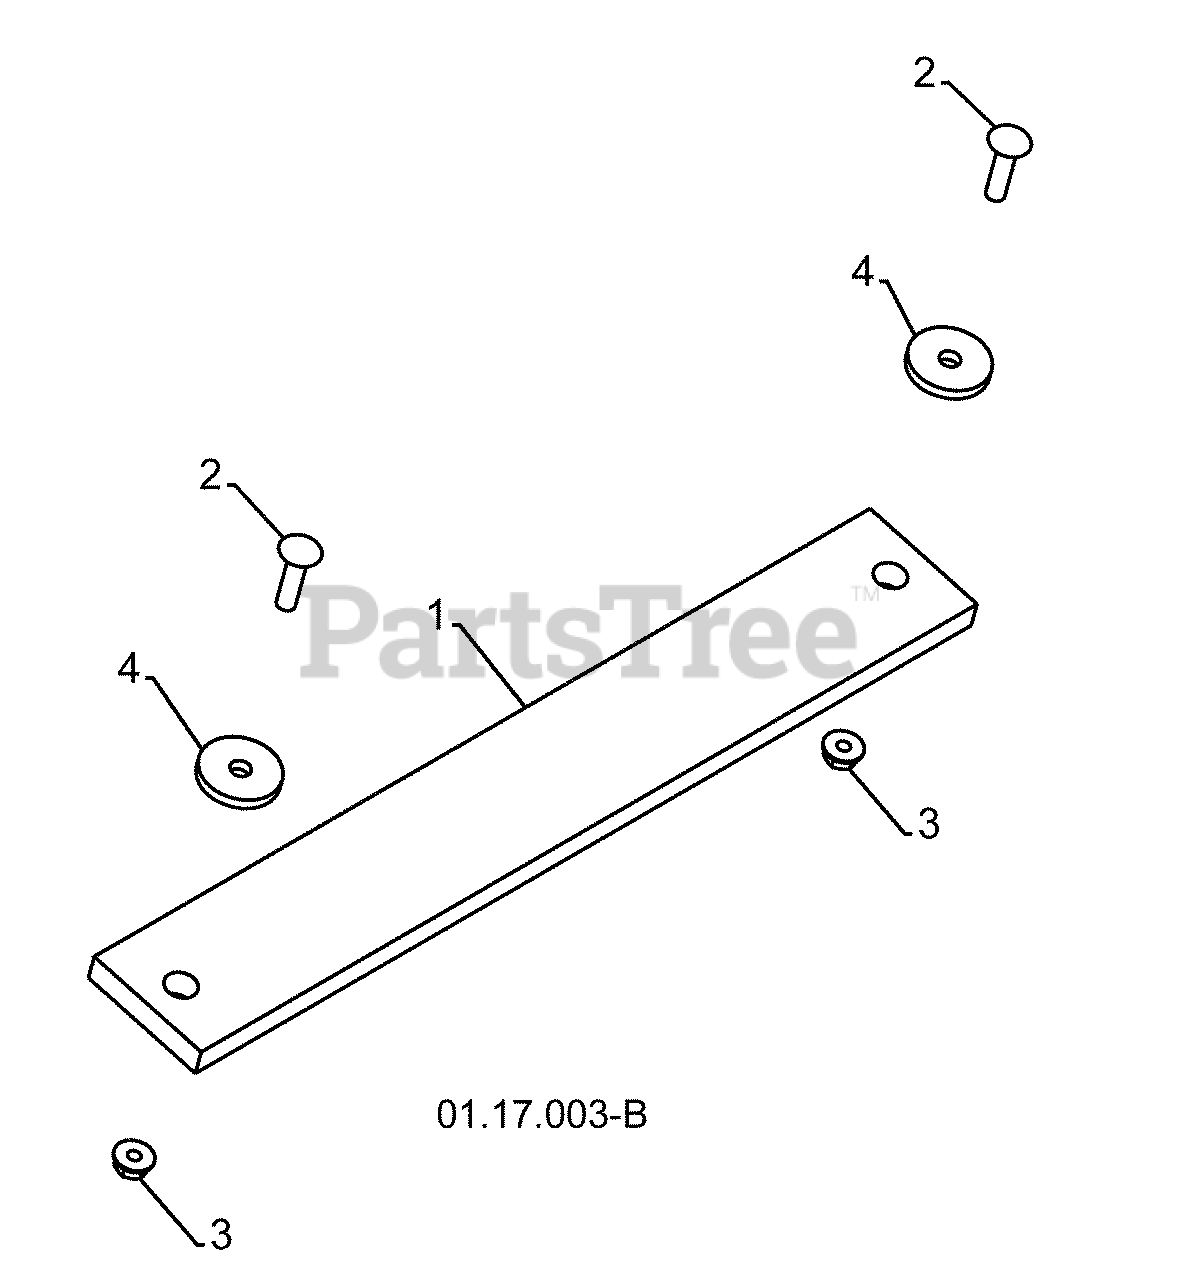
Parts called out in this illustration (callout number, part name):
1	WEIGHT BAR
2	CARRIAGE BOLT 5/16-18 X 1.25
3	NUT 5/16-18
